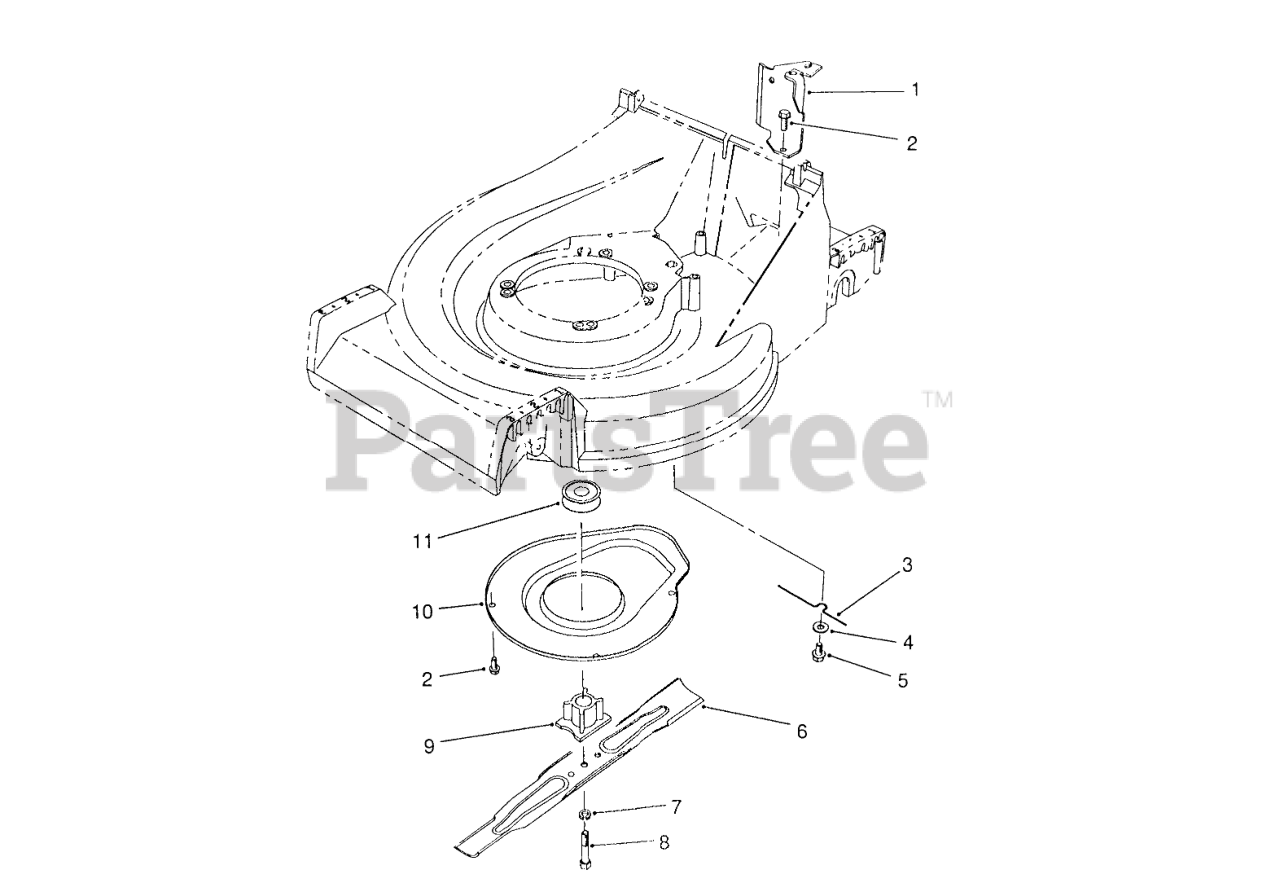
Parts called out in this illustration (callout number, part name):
1	Bracket-Cable Support
2	SCREW-HWHTF
3	RETAINER-BELT
4	WASHER-FLAT
5	SCREW-HHFTF
6	Key
7	WASHER-LOCK
8	SCREW-BLADE
9	BLADE RETAINER
10	Cover
11	PULLEY-DRIVE, ZONE START
